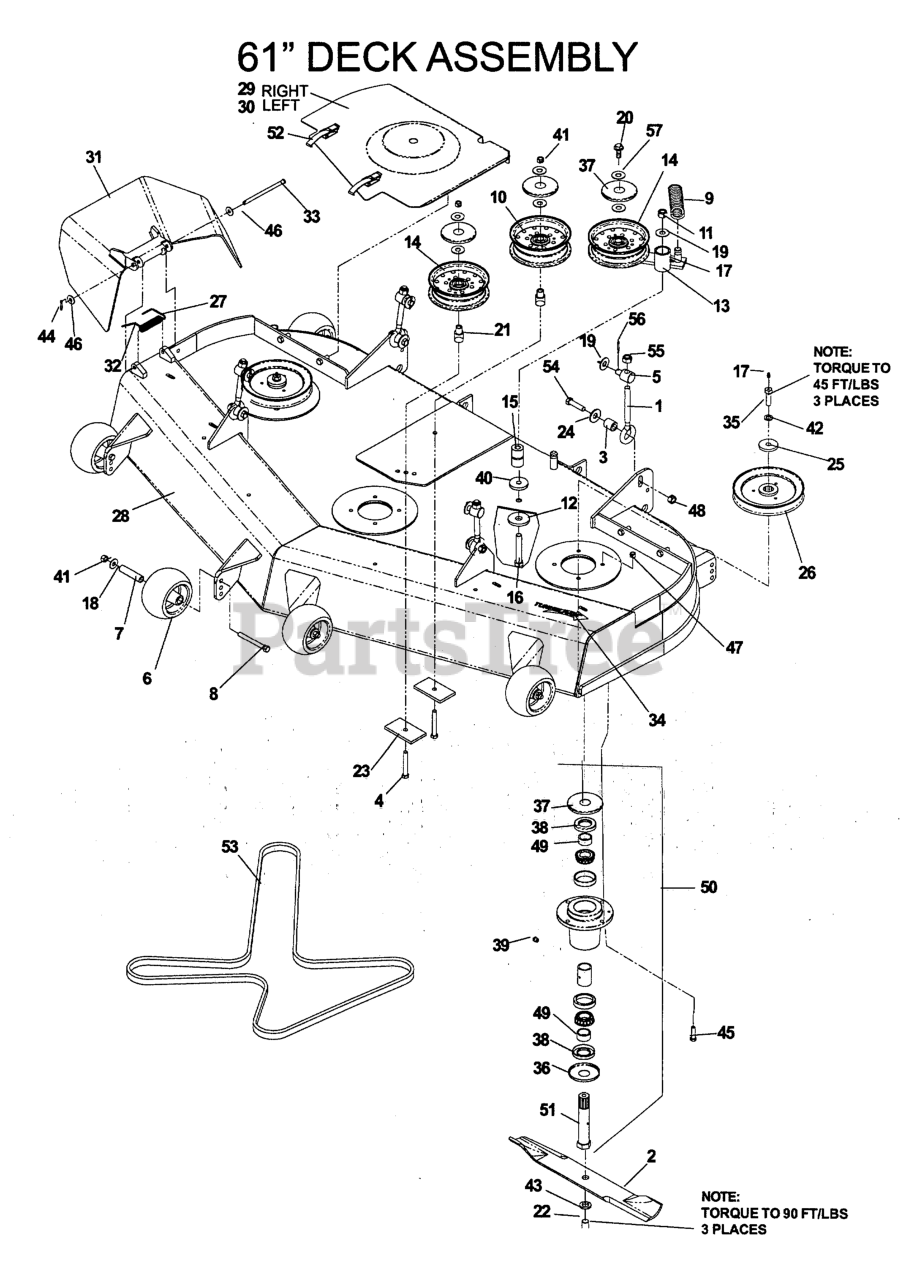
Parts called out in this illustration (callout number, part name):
2	BLADE OEM 21" (61" DECK)
4	SCREW 3/8C X 2 3/4 HEX CAP
6	ANTI-SCALP ROLLER
8	HCS 3/8C X 3 1/2
9	DECK SPRING
10	IDLER PULLEY (TALL)
11	NUT 1/2-13 HEX NYLOC ZD
12	WASHER, SUPPORT
14	IDLER PULLEY
15	PIVOT BUSHING
16	HCS 1/2C X 3 1/4
17	ZERK
18	WASHER 3/8 FLAT
19	WASHER 1/2 FLAT
20	4CS 3/8C X 1 SERRATED HEAD
21	IDLER BUSHING
22	HCS 5/8F X 1 1/4
23	SUPPORT PLATE
24	SPRING WASHER - .50
25	SPINDLE WASHER
26	RP PULLEY - 61"
27	CAP-SLEEVE
28	DECK W/DECALS 61" HUS
29	61 BELT SHIELD ASM - RH
30	61 BELT SHIELD ASM - LH
31	DISCHARGE CHUTE 61"
32	SPRING - TORSION
33	PIN-CLEVIS 5/16 DIA X 5.19 ZD
34	DECAL, TUNNEL RAM 8"
35	HCS 7/16-20 GD 8 SPEC
36	BOTTOM DUST CAP
37	TOP DUST CAP
38	SHAFT SEAL
39	PLUG-VENTED
40	WASHER 1/2 X 1.44 HRD ZD
41	NUT 3/8-16 NYLOC
42	WASHER 7/16 LOCK
43	LOCKWASHER 5/8
44	RP_COTTER PIN 1/8 X 3/4
45	HCS 5/16C X 1 1/4
46	WASHER 5/16 FLAT
47	NUT 5/16 NYLOC
48	NUT 7/16C CENTERLOCK
50	SPINDLE ASSY - 52/61"
51	SPINDLE 52/61
52	DRAW LATCH
53	BELT, DECK 61"
54	HCS 7/16 - 14 X 1 3/4
55	NUT 1/2-13 HEX NYLOC ZD
56	PIN COTTER 1/8 X 1 ZD
57	WASHER, 3/8 SPEC
